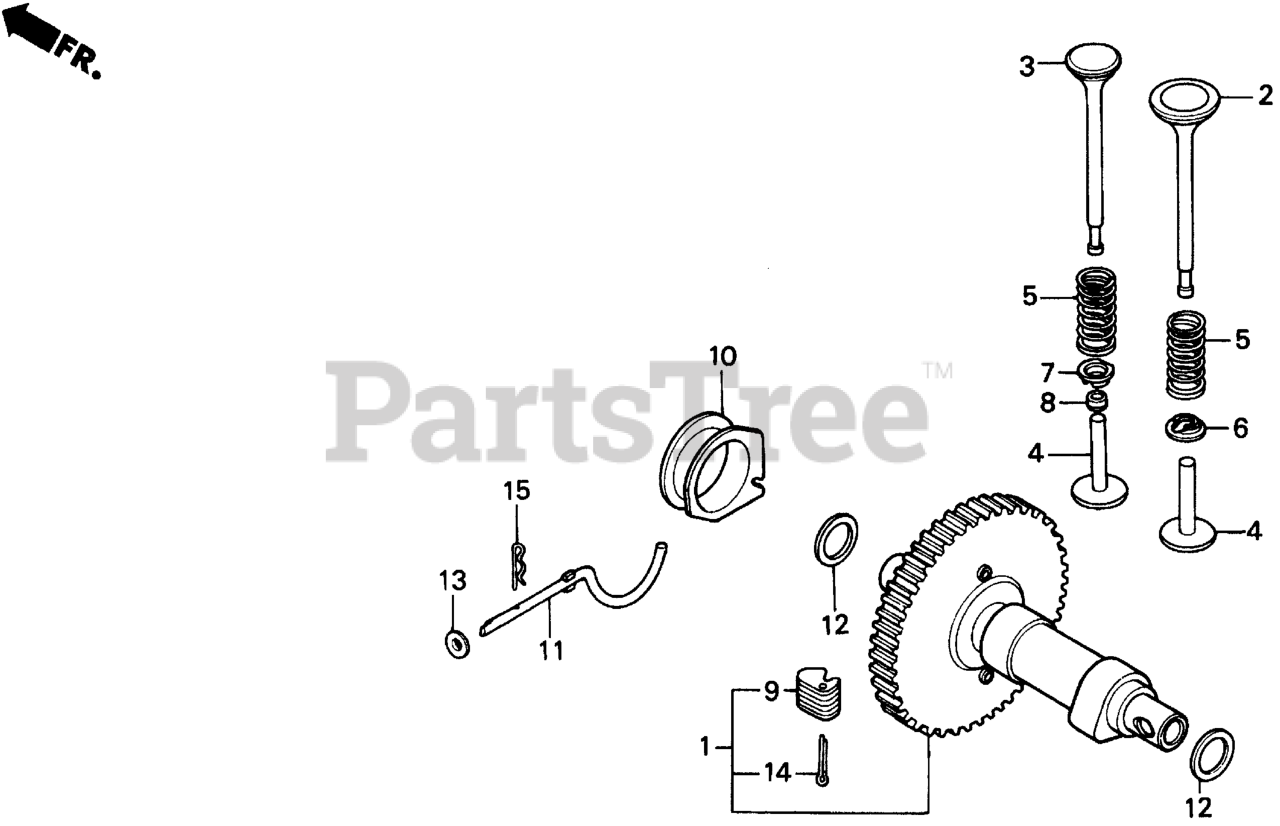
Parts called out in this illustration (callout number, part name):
1	CAMSHAFT ASSY.
2	VALVE, IN.
3	VALVE, EX.
4	LIFTER, VALVE (45.89MM)
4	LIFTER, VALVE (46.04MM)
4	LIFTER, VALVE (46.19MM)
4	LIFTER, VALVE (46.34MM)
5	SPRING, VALVE
6	RETAINER, VALVE SPRING
7	RETAINER, VALVE SPRING
8	ROTATOR, EX. VALVE
9	WEIGHT, GOVERNOR
10	SLIDER, GOVERNOR
11	SHAFT, GOVERNOR
12	WASHER, THRUST (18MM)
13	WASHER, PLAIN (6MM)
14	PIN, SPLIT (3.0X25)
14	PIN, COTTER (3.0X45)
15	PIN, LOCK (10MM)
